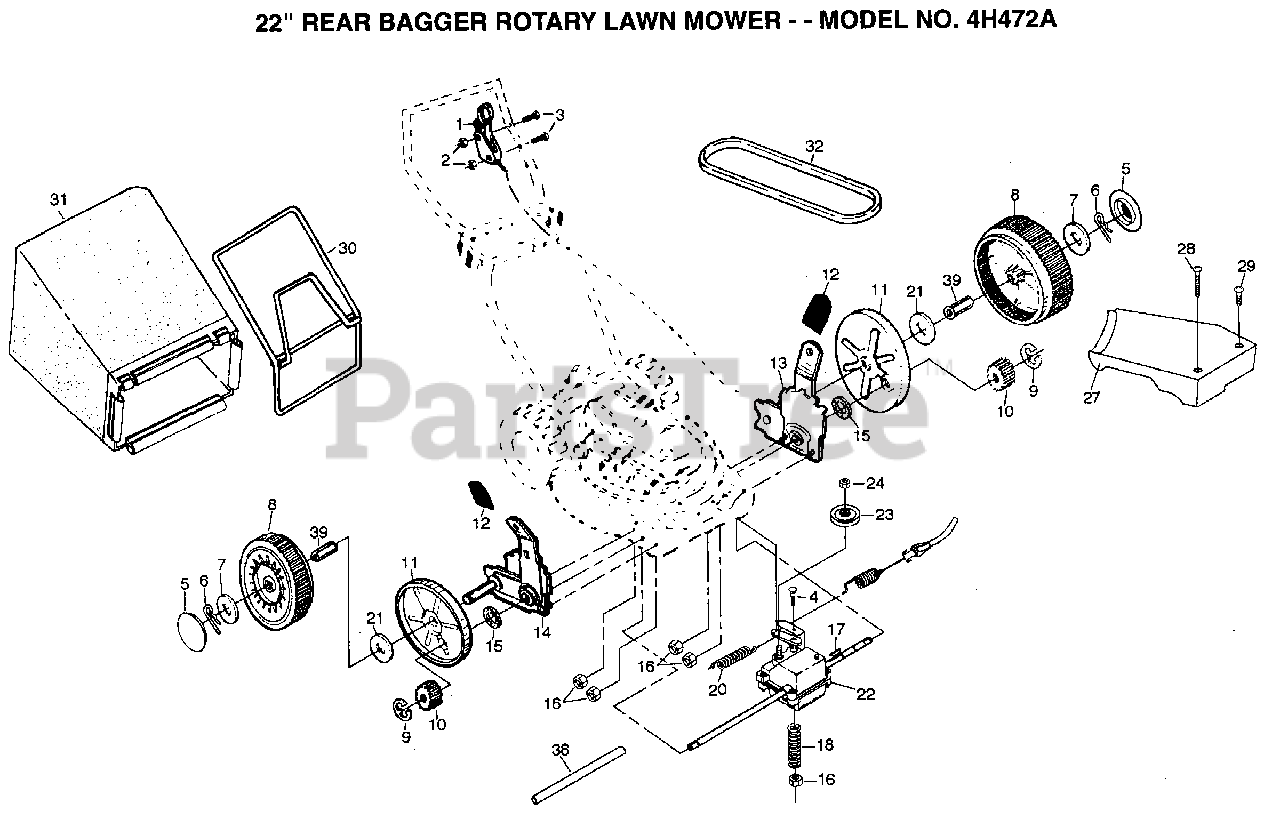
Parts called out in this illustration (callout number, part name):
1	CONTROL.DRIVE
3	SCREW
4	BOLT.1/4-20X2.0
5	HUB CAP
6	RETAINER CLIP PM
7	WASHER
8	WHEEL.8X2.LP.PR
10	PINION.GEAR
11	DUST SHROUD PM
12	KNOB PM
15	WASHER PM
17	HI PRO KEY
18	SPRING.TENSION
20	SPRING
21	WASHER FLUT
23	PULLEY.DRIVEN
24	LOCKNUT
27	"COVER.DRIVE 22""RD"
30	CATCHER FRAME
31	GRASS BAG
38	DRV SHAFT TUBE PM
39	BUSHING.HEX
